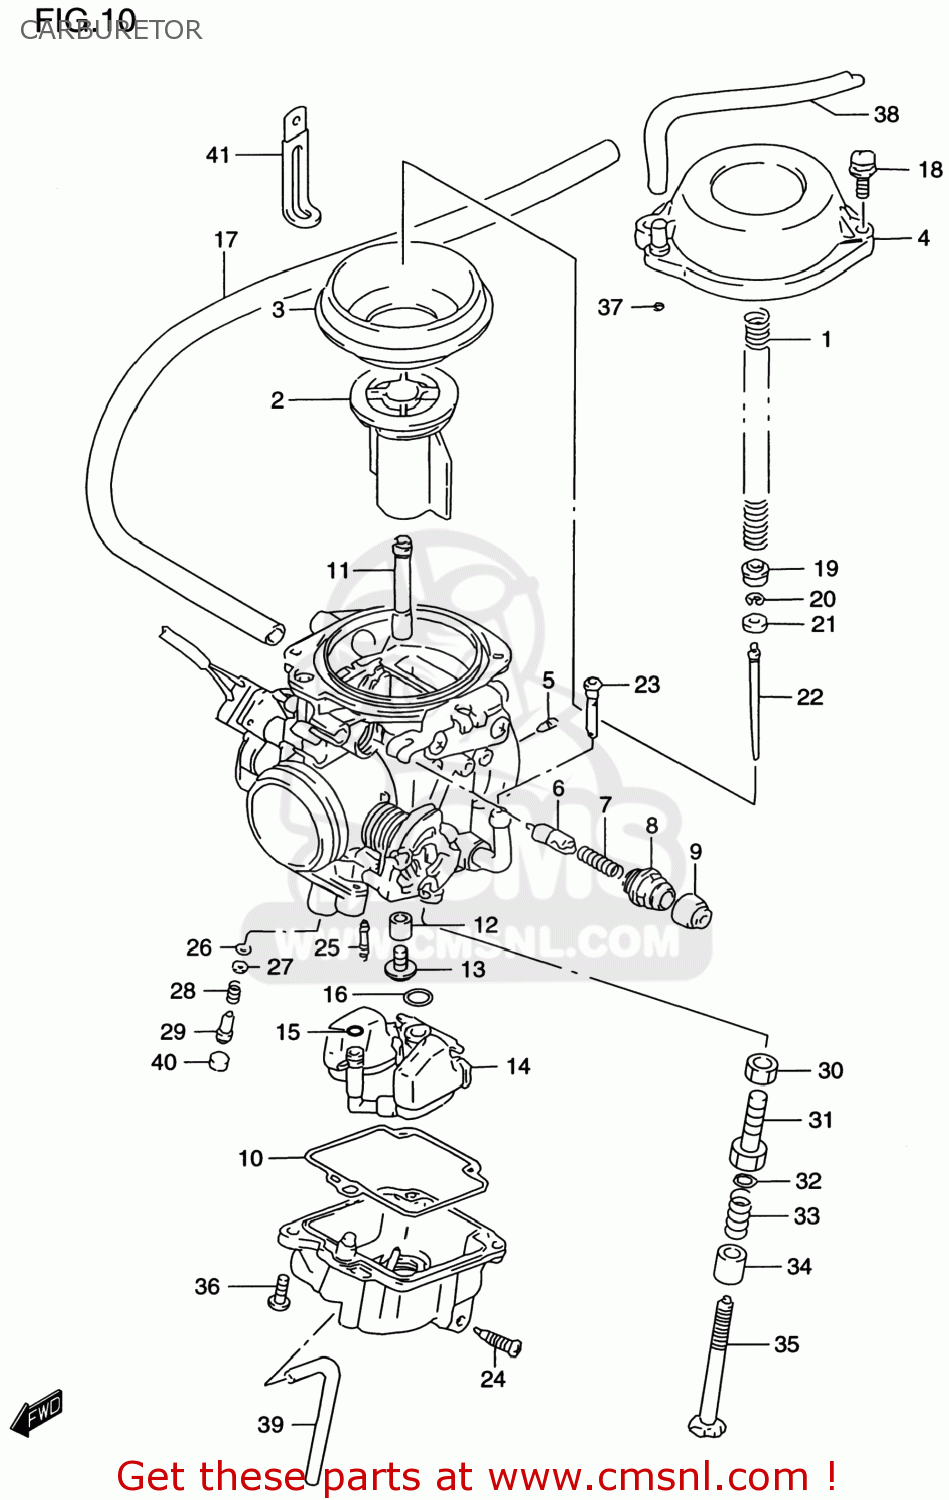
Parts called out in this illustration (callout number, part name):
1	SPRING
2	VALVE,PISTON
3	DIAPHRAGM
4	COVER,DIAPHRAGM
5	JET,AIR(1.0)
6	PLUNGER
7	SPRING
8	HOLDER,GUIDE
9	CAP
10	GASKET,FLOAT CHAMBER (NAS)
11	JET,NEEDLE
12	RING
13	JET,MAIN(140)
14	FLOAT/NEEDLE VALVE ASSEMBLY
15	O RING
16	O-RING,NEEDLE VALVE
17	HOSE(6.5X10.5X275)
18	SCREW
19	RING
20	CLIP,NEEDLE
21	RING
22	NEEDLE,JET
23	FILTER
24	SCREW,DRAIN
25	JET,PILOT(42.5)
26	O RING,PILOT AIR SCREW
27	WASHER
28	SPRING
29	SCREW,PILOT
30	NUT
31	ADJUSTER
32	WASHER,STARTER SHAFT
33	SPRING
34	RING
35	ADJUSTER
36	SCREW(5X14)
37	O RING
38	HOSE(4.5X8.5X600)
39	HOSE (3X5X425)
40	PLUG
41	CLAMP(L:65)
